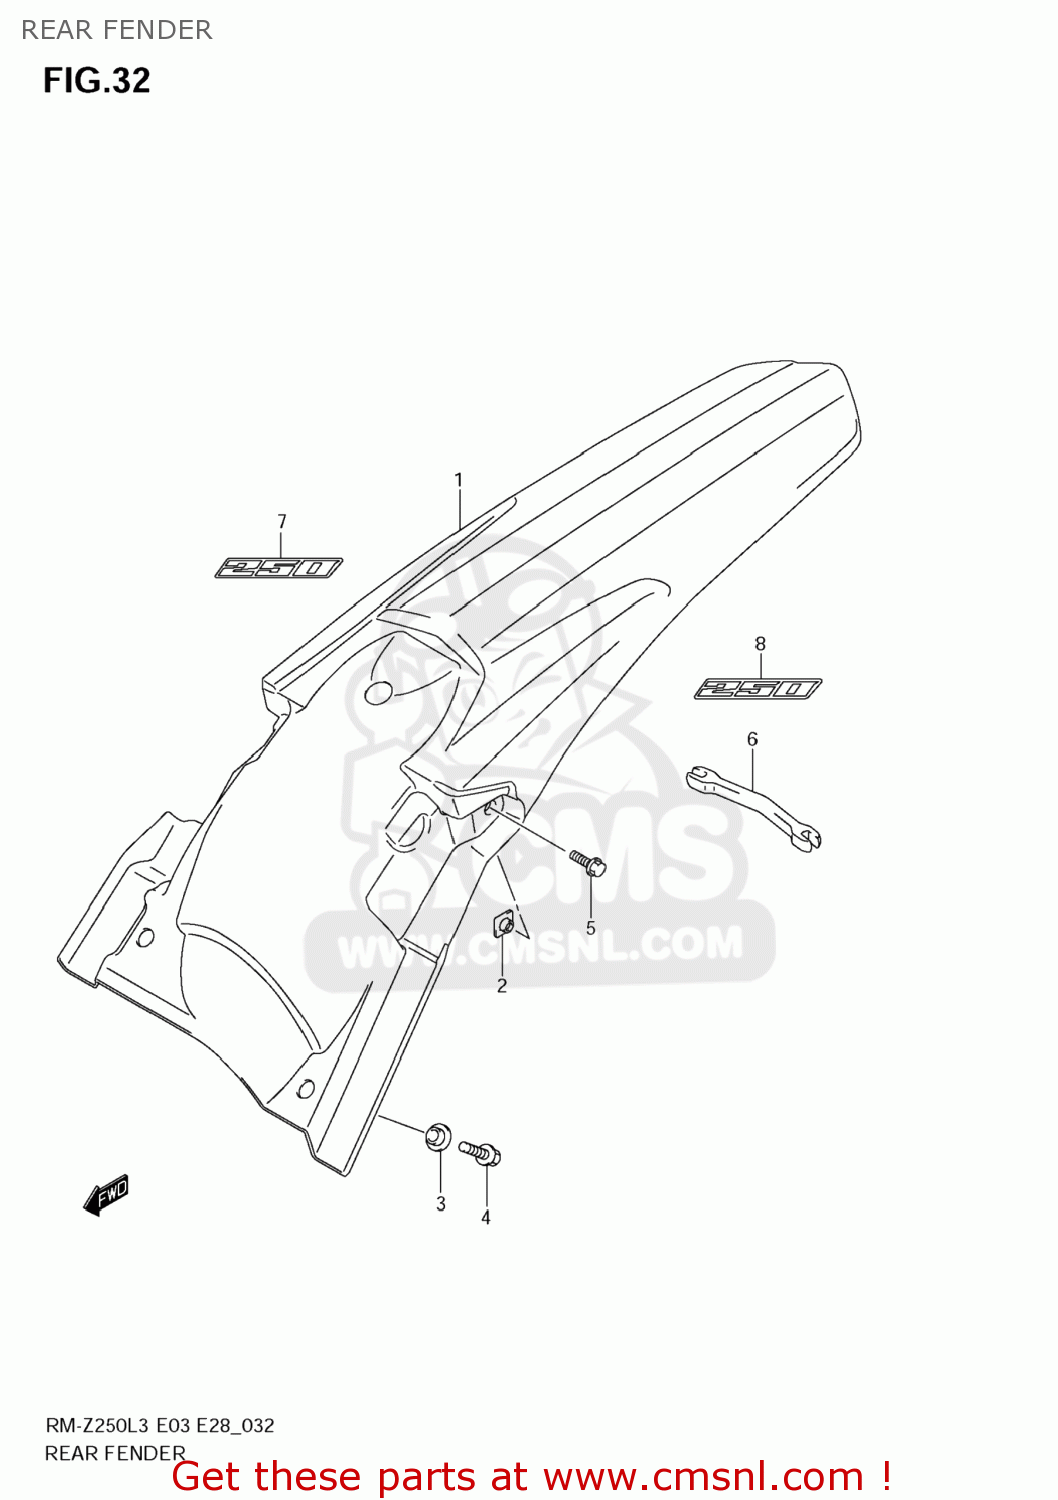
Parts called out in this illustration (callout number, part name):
1	FENDER,RR
2	NUT,RR REFLECTOR
3	WASHER,FR FENDER
4	BOLT
5	BOLT
6	OPEN SPANNER(6.4X6.8)
7	EMBLEM,RR FENDER,R
8	EMBLEM,RR FENDER,L
